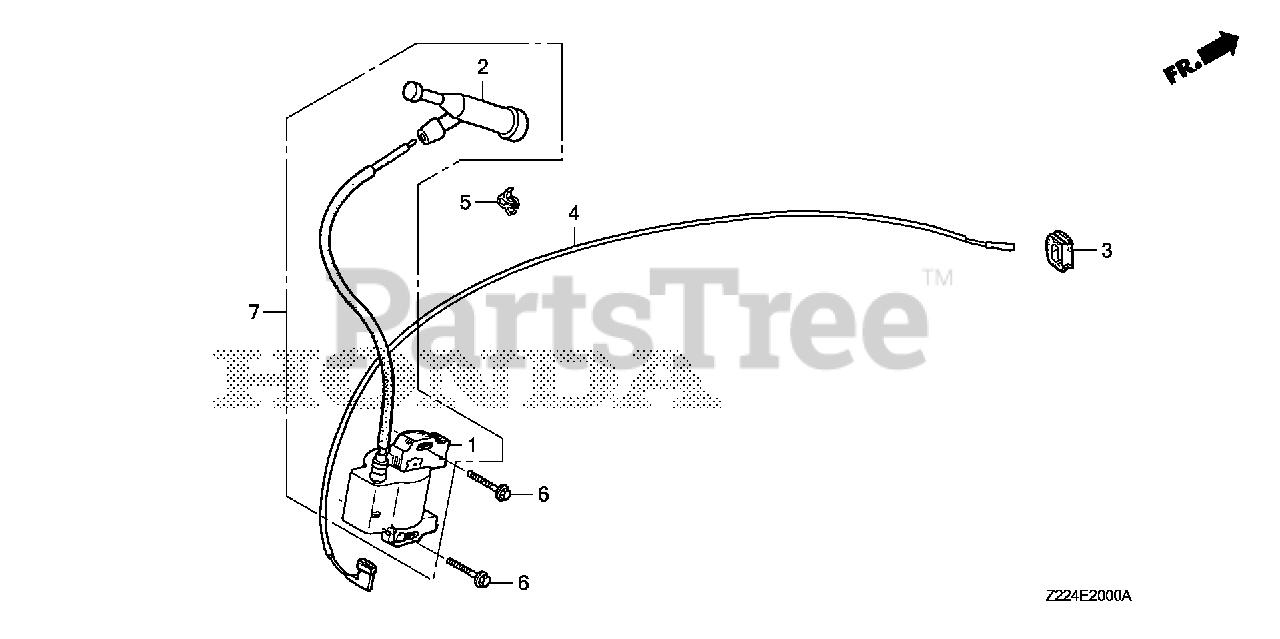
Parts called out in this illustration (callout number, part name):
3	GROMMET, WIRE
4	WIRE, STOP SWITCH (470MM)
5	HOLDER, STOP SWITCH WIRE Use up to Engine SN 2056819.
6	BOLT, FLANGE (6X28) (CT200) Use up to Engine SN 1530314.
7	COIL ASSY., IGNITION & CAP ASSY. NOISE SUPPRESSOR
